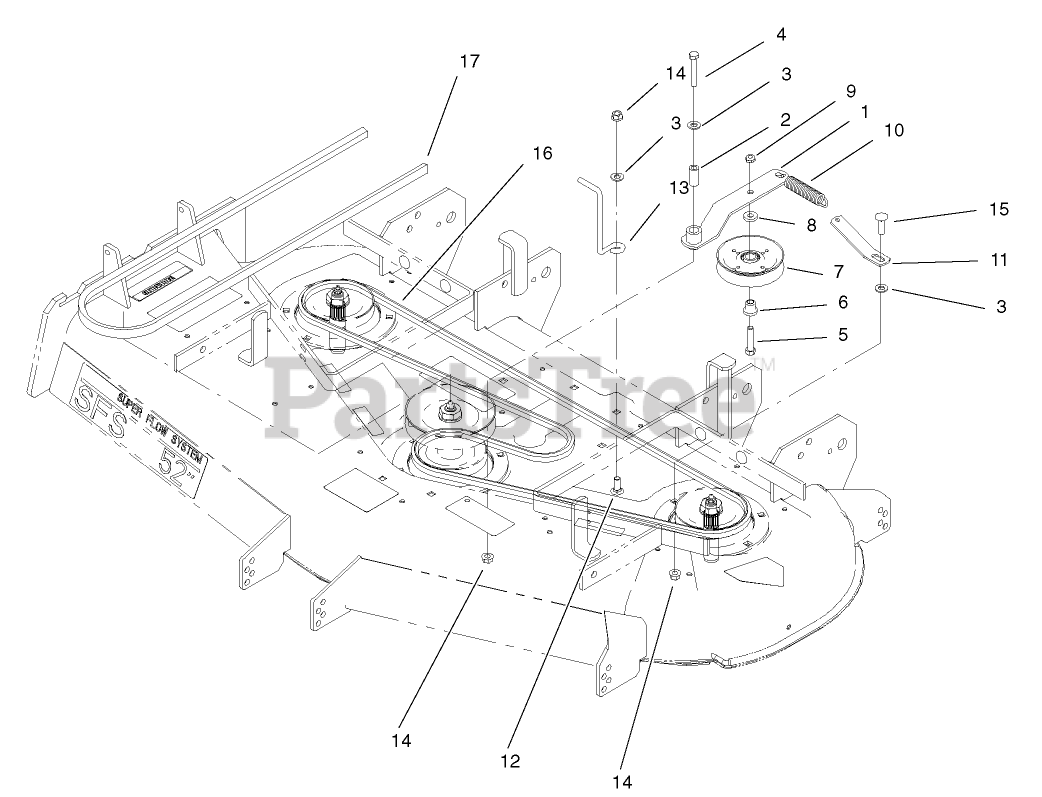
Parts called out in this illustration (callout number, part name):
1	IDLER ARM ASM
2	SLEEVE
3	WASHER-FLAT
4	SCREW-HH
5	SCREW-HH
6	BUSHING-PULLEY
7	PULLEY-IDLER
8	WASHER-FLAT
9	NUT-HEX
10	SPRING-EXTENSION
11	PLATE-SPRING
12	SCREW-CARR
13	GUIDE-BELT
14	NUT-HF
15	SCREW-CARR
16	V-BELT
17	BELT (52)
